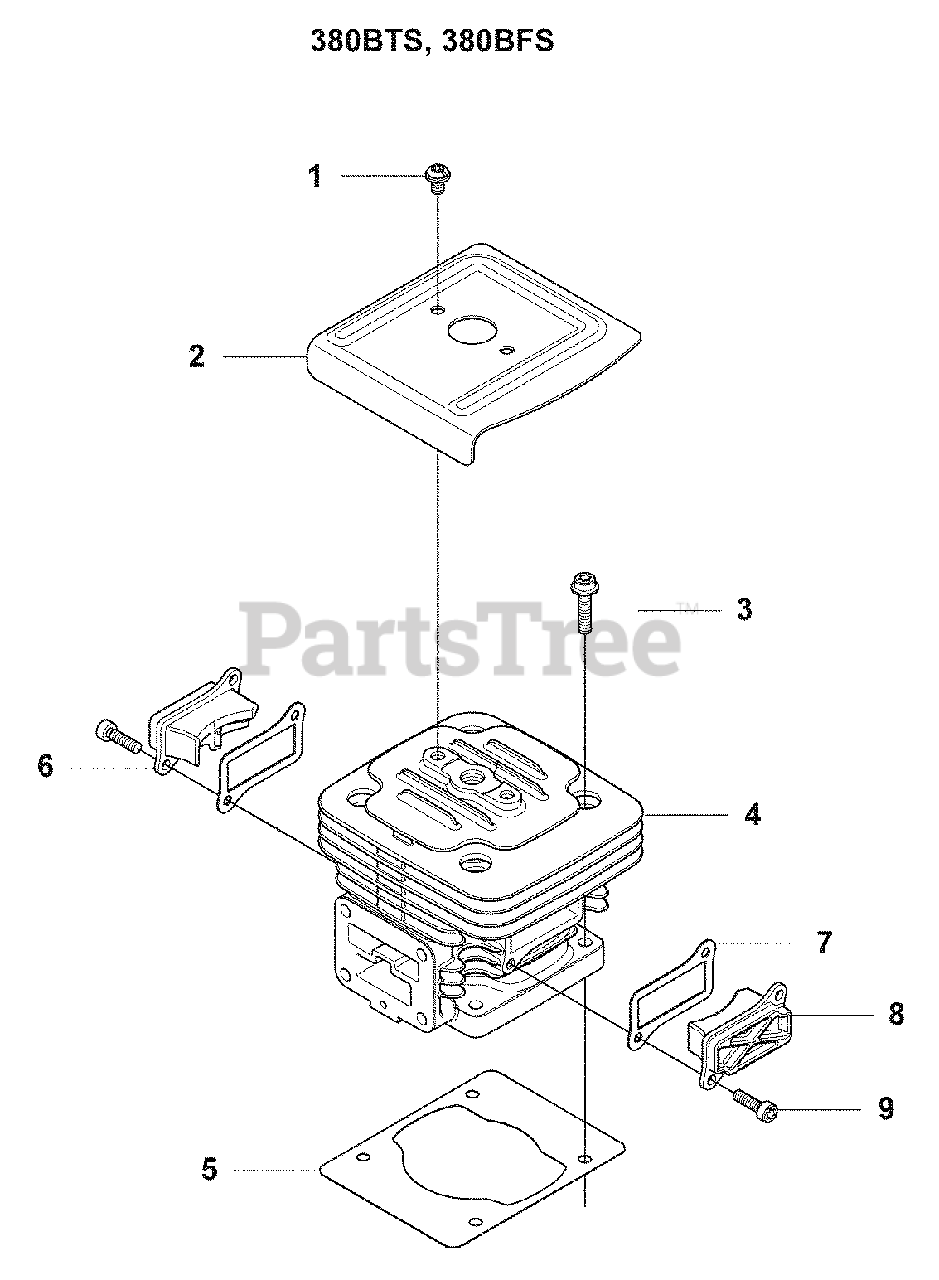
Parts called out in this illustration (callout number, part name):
3	Torx Bolt
5	Gasket
6	Cover, TR F
7	Gasket
9	Torx Bolt, M4 X L16
